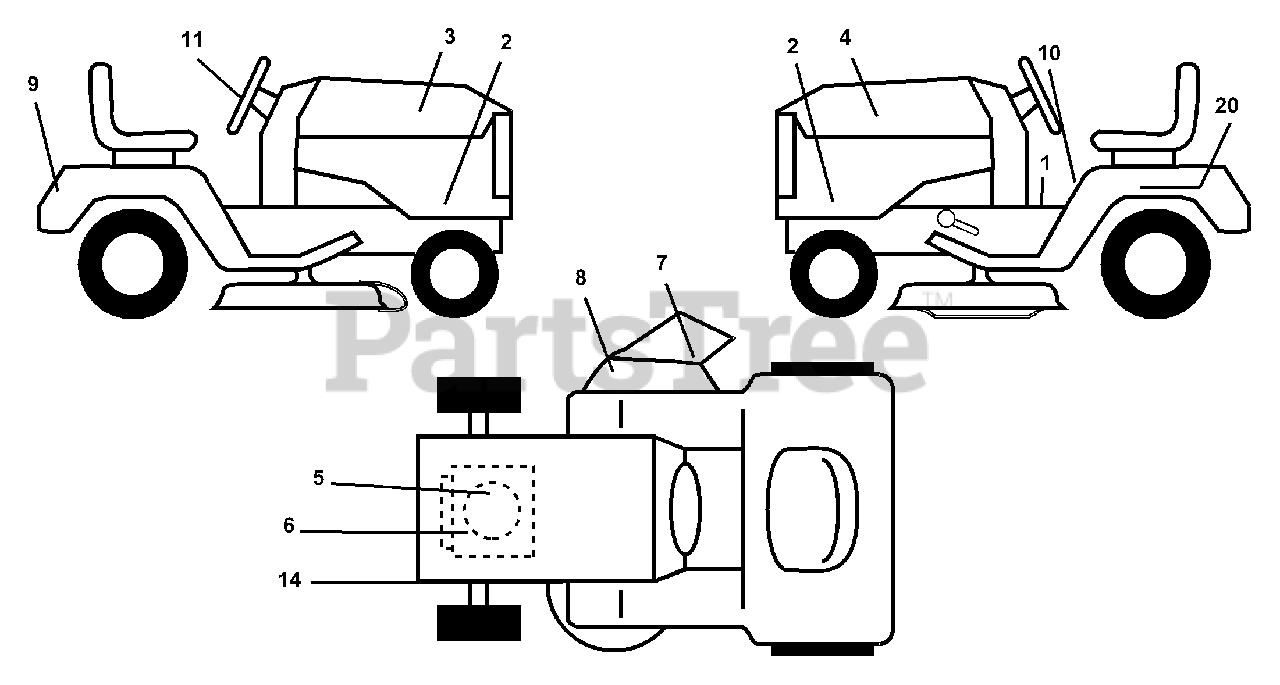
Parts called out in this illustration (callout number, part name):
1	Decal Oper. Step Thru Eng/Fr
2	Decal Side Panel
3	Decal Hood RH
4	Decal Hood LH
5	Decal Hood Cust.
6	Decal Engine
7	Decal Deck B 42
8	Decal Warning
9	Decal Fender Husq
10	Decal Fender Danger Eng/Fr
11	Decal SW Husq Prem
14	Decal V-Belt Schematic
20	Decal Bat Dan/Psn
